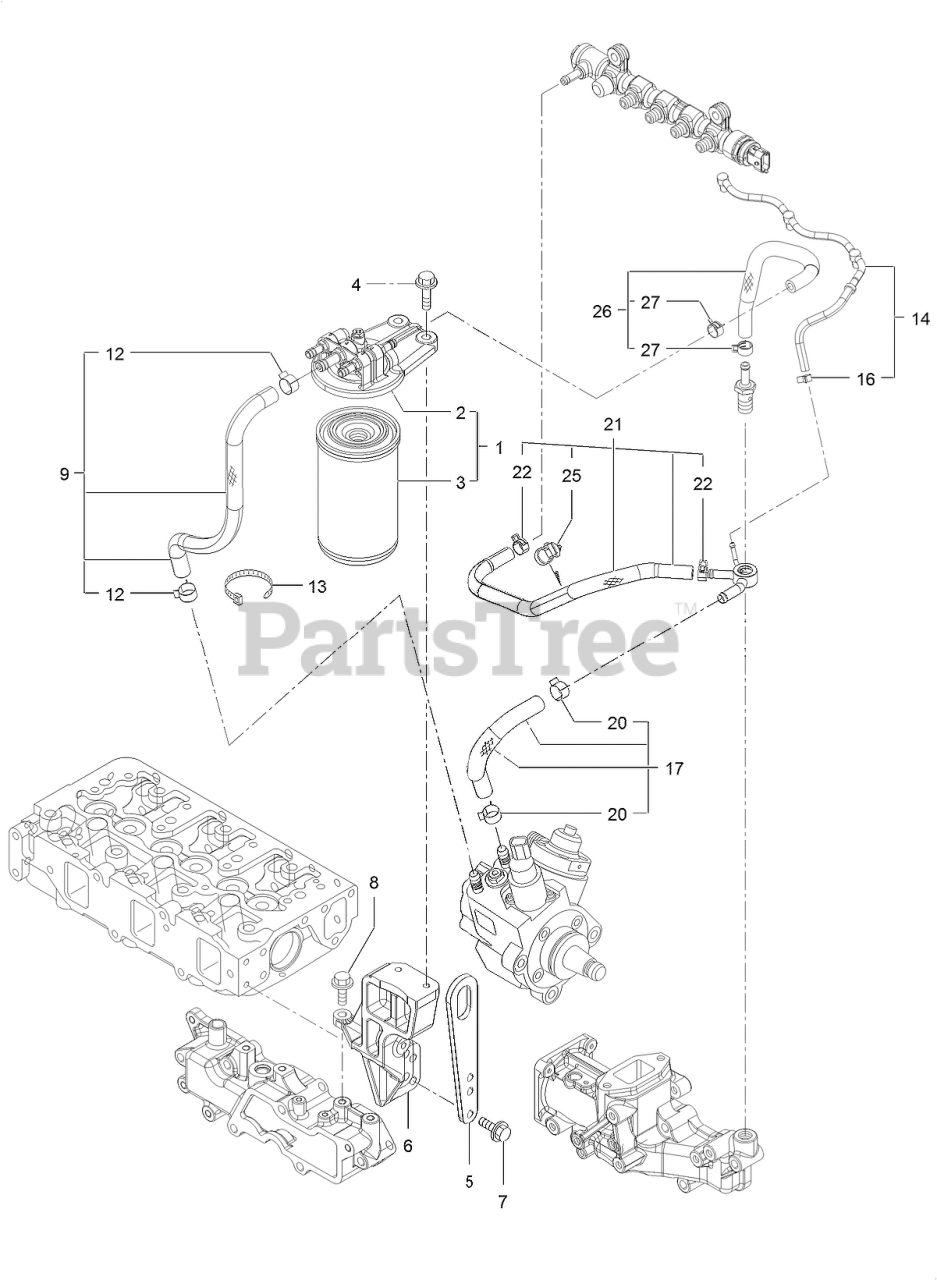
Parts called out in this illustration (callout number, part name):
1	FUEL/OIL FILTER ASM
2	FUEL/OIL FILTER BRACKET A
3	FILTER-FUEL/OIL
6	FILTER BRACKET ASM
9	FUEL PIPE ASM
12	CLAMP-HOSE
14	PIPE ASM-FO RETURN
16	CLAMP-HOSE
17	FUEL PIPE ASM
20	CLAMP-HOSE
21	FUEL PIPE ASM
22	CLIP-HOSE
25	BAND-CLIP
26	FUEL PIPE ASM
27	CLIP-HOSE
